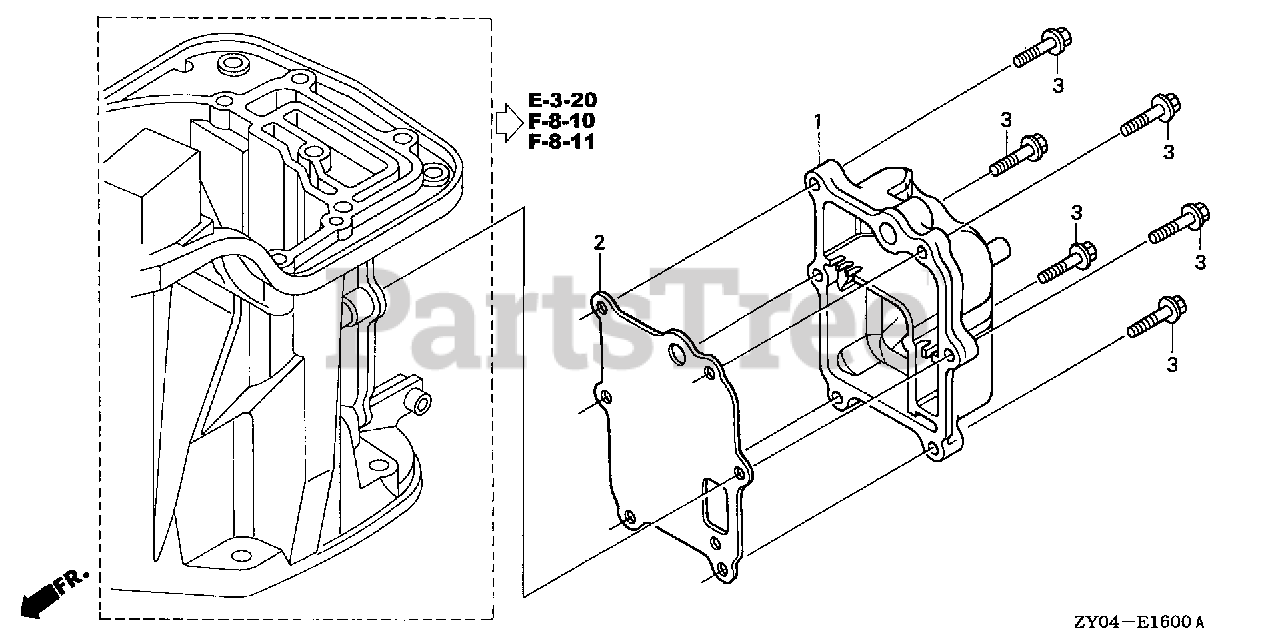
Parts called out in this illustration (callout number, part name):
1	COVER, EX. CHAMBER
2	GASKET, EX. CHAMBER
3	BOLT, FLANGE (6X23)
